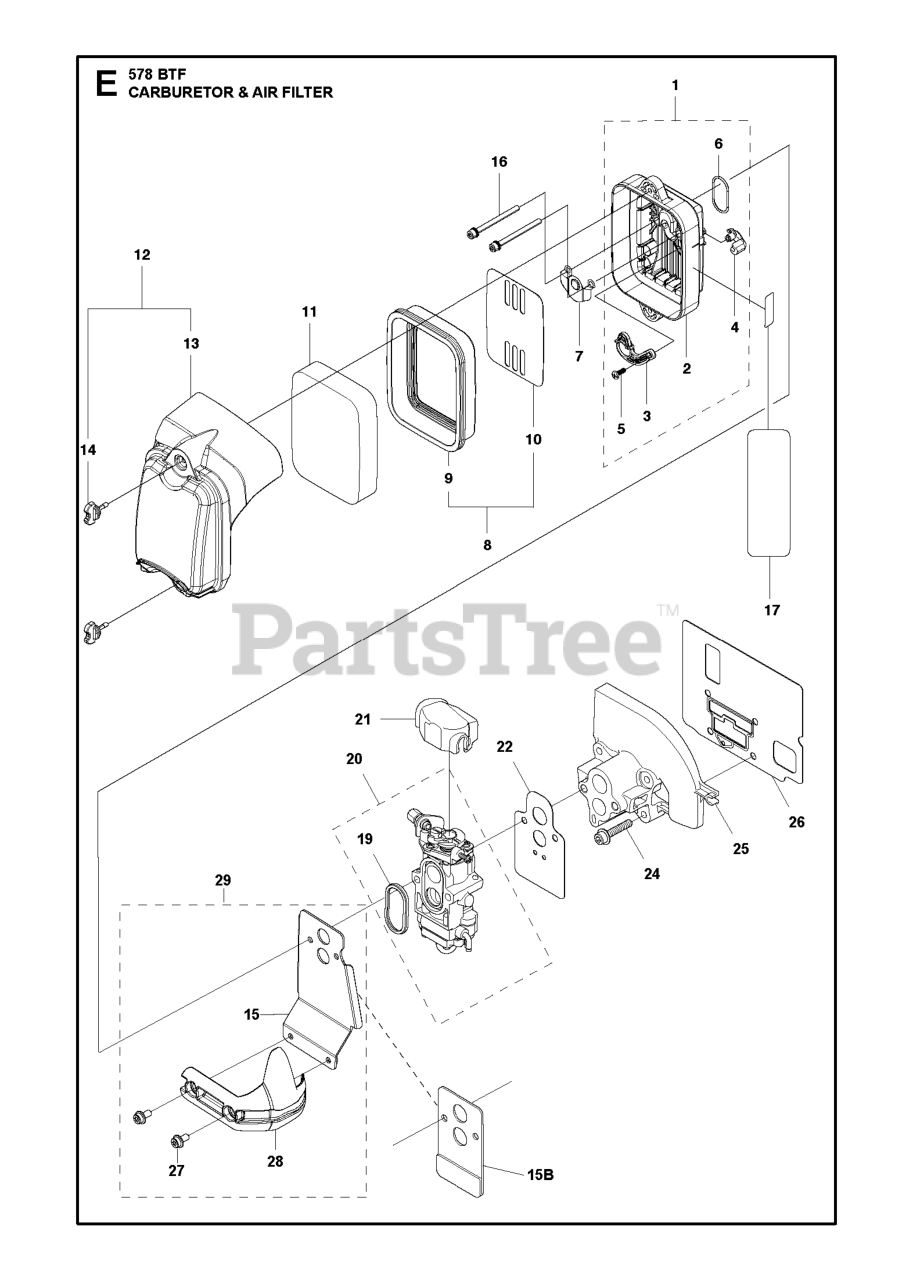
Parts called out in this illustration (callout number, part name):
1	AIR FILTER HOLDER ASSY
2	AIR FILTER HOLDER
10	SCREEN
11	AIR FILTER
12	AIR FILTER COVER
13	AIR FILTER COVER
17	LABEL,CHOKE
27	BOLT (RPLS T495051010-11)
